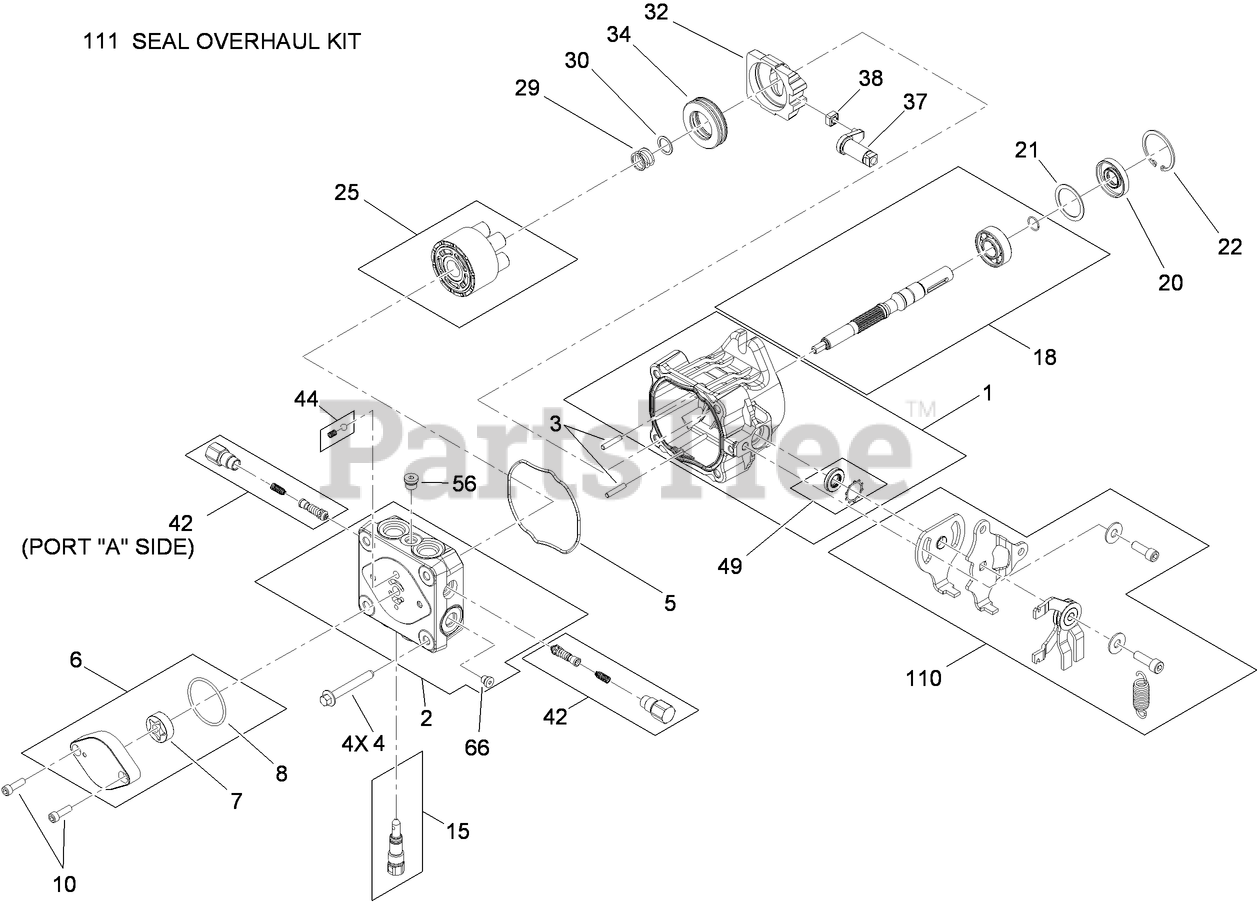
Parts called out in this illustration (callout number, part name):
1	HOUSING KIT
2	END CAP STD CHARGE KIT
3	PIN-HEADLESS, STRAIGHT
4	BOLT-HF
5	O-RING
6	CHARGE PUMP KIT
7	GEROTOR ASM
8	O-RING
10	CAPSCREW
15	BYPASS VALVE KIT
18	INPUT SHAFT KIT
20	SEAL-LIP
21	SPACER
22	RING-RETAINING
25	CYLINDER BLOCK KIT
29	SPRING-BLOCK
30	WASHER-THRUST
32	SWASHPLATE-VARIABLE
34	BEARING-THRUST
37	ARM-TRUNNION, TAPERED SQUARE
38	GUIDE-SLOT
42	VALVE-CHECK (W/POPPET)
44	CHARGE RELIEF KIT
49	TRUNNION SEAL / RETAINER KIT
56	PLUG-HSH
66	PLUG-HSH
110	KIT-RETURN
111	SEAL OVERHAUL KIT
